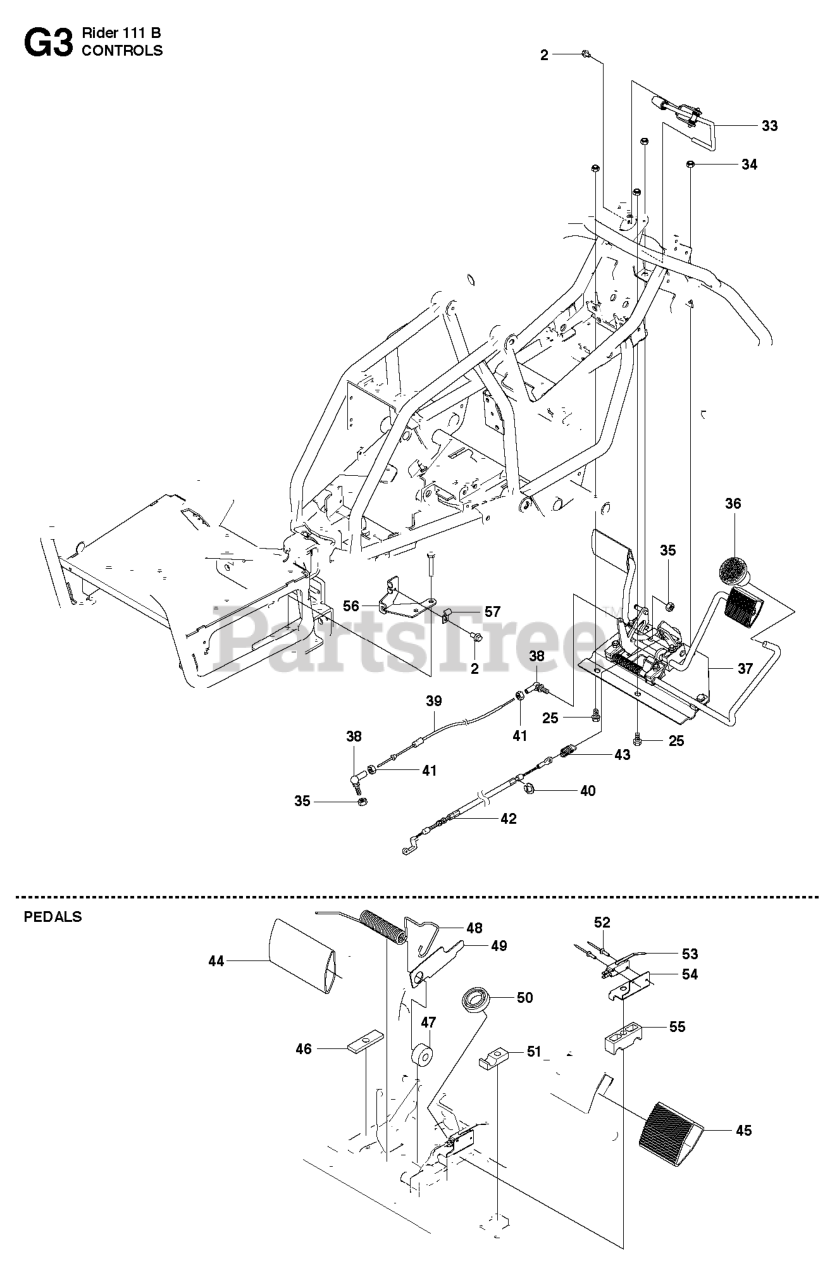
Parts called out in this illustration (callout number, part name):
33	LOCKING LEVER
36	KNOB
37	PEDAL ASSEMBLY
38	CONNECTOR
39	CONTROL CABLE
41	LOCKNUT M5
44	PEDAL RUBBER, SF
45	PEDAL RUBBER
46	PLATE
47	ROLLER
48	SPRING
49	PLATE
50	BALL BEARING 6002-2RS1
51	SUPPORT
53	MICRO SWITCH
55	PEDAL SHAFT CLAMP
56	WIRE HOLDER
